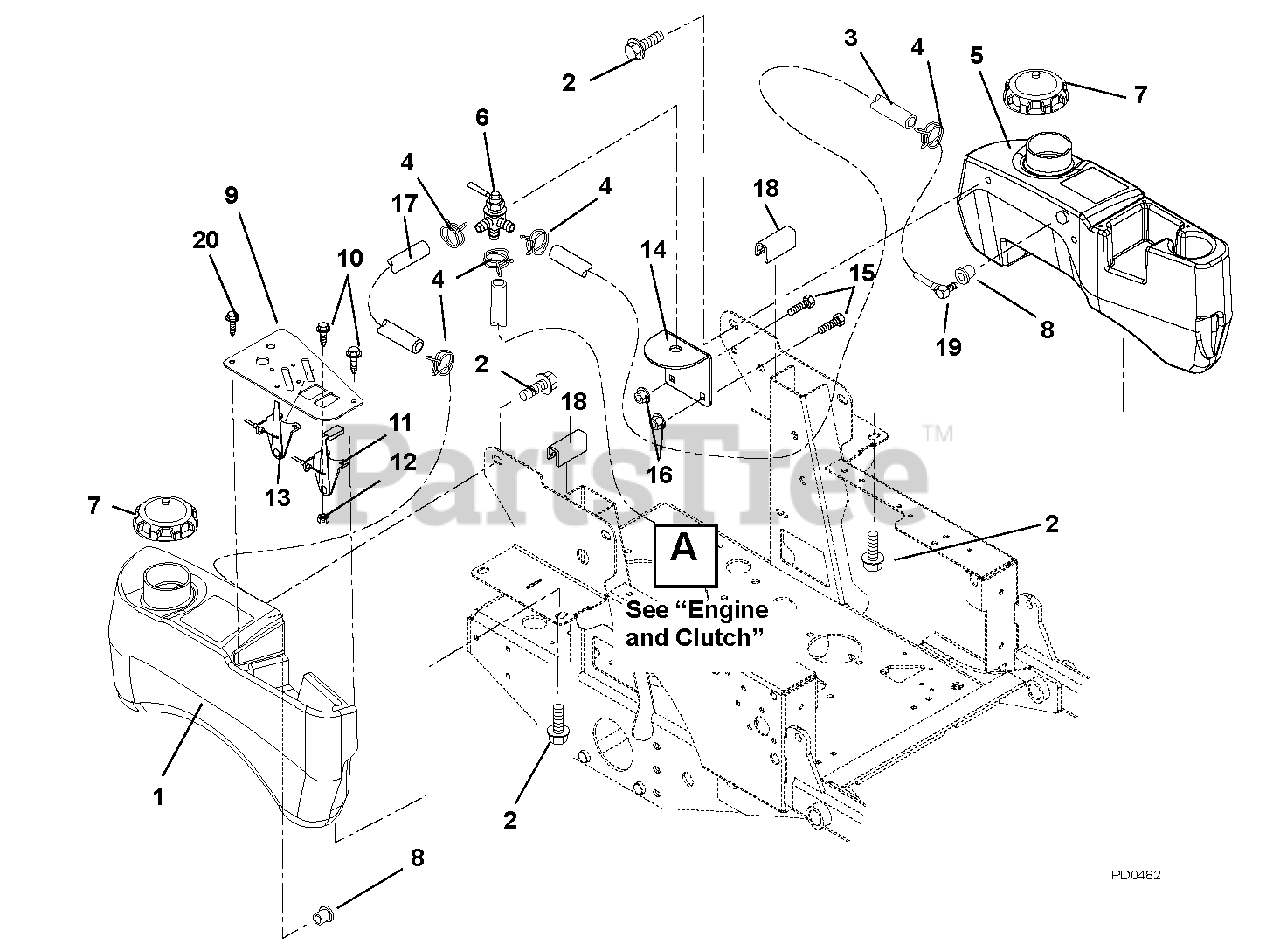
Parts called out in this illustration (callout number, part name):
1	Tank, Fuel Right Hand (S/N 101-2499) 991301 Only
2	Bolt, SEMS .31-18 x .62 (S/N 101-2499)
3	Hose, Gas Line .25" I.D.
4	Hose, Clamp
5	Tank, Fuel Left Hand (S/N 101-2499)
6	Valve, Fuel
7	Cap, Fuel (S/N 101-2499)
8	Grommet (Orange color will not replace black color)
9	Panel, Control
10	Screw, Machine 10-24 x .50 Hex Washer Head
11	Cable, Throttle
12	Nut, Locking Nylon 10-24 With Insert
13	Cable, Choke
14	Bracket, Fuel Valve Mounting
15	Bolt, Round Head Square Neck .31-18 x .75
16	Nut, Nyloc Flange 5/16-18
17	Hose, Gas Line .25" I.D.
18	Cowl Strip 1.75" Long
19	Assembly, Small Tank Fuel Pick-up
20	Screw, Machine 10-24 x .38
